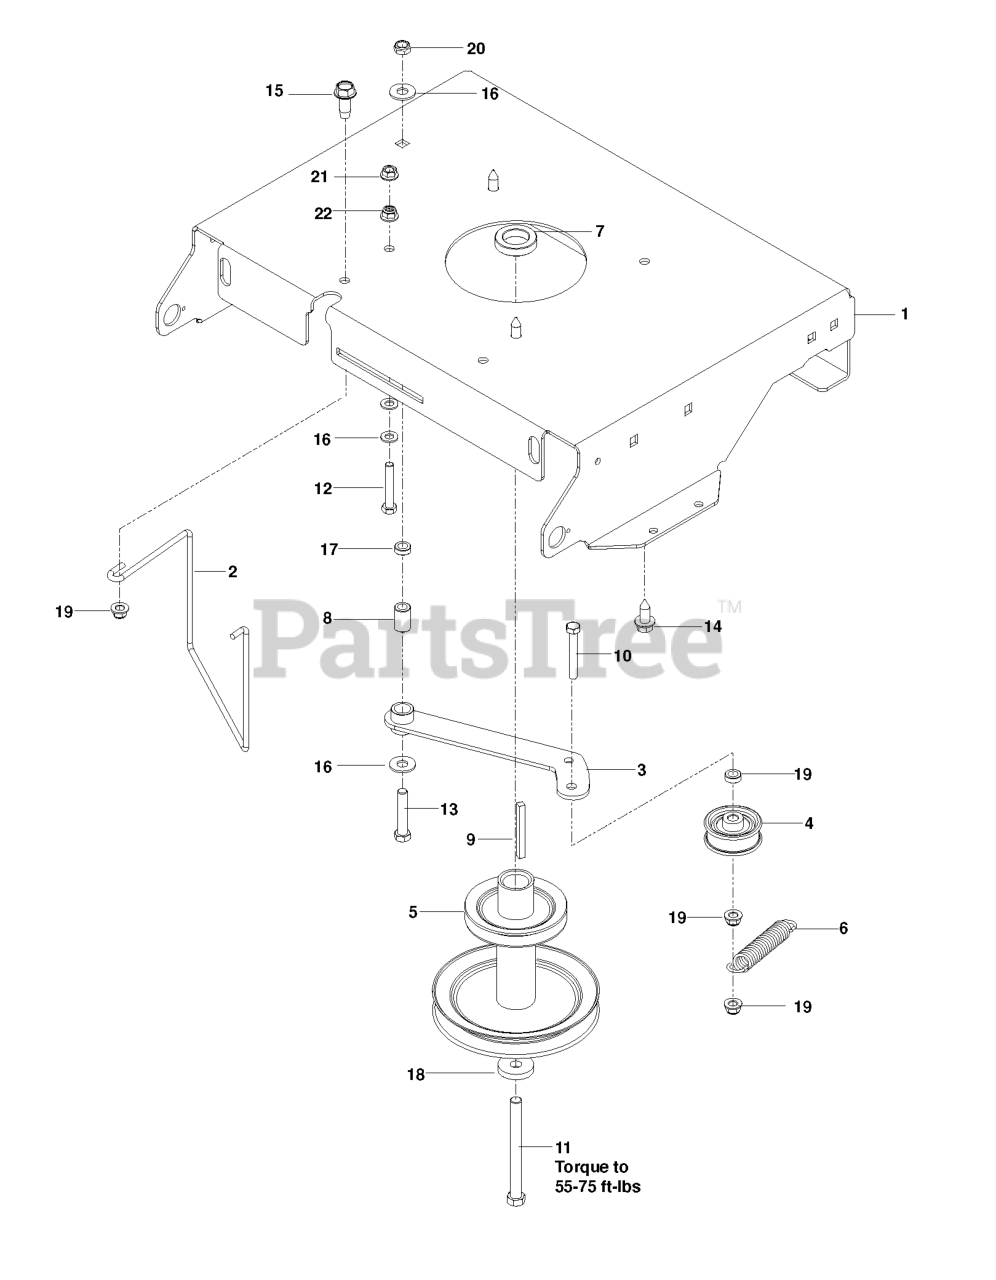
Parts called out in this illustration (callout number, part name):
1	PLATE.ENGINE.ORG
2	KEEPER, BELT ENGINE
3	!DLER ARM WLDMNT, BLACK
4	PULLEY IDLER
5	PULLEY, ENGINE 6.5
6	SPRING - 3.50
9	KEY 1/4 SQ X 2-1/2
10	TAPBOLT, 3/8C X 3
11	HCS 7/16-20 X 4 GR5 ZD
12	HCS 5/16-18X2
13	HCS 3/8C X 2
14	HHFS 3/8-16 X 1.0 THD FORMING
15	BOLT 3/8-16 X 1.0
16	FLAT WASHER 5/16 SAE
17	WASHER 3/8 X 3/4 X .187 TK
18	WASHER .43X1.38X.25
19	NUT 3/8-16 HEX FLG NYLOC ZD
20	NUT HEX 3/8-16 NYLON, THIN
21	NUT 5/16C WHIZ
22	5/16-18 NYLOC FLANGE NUT
